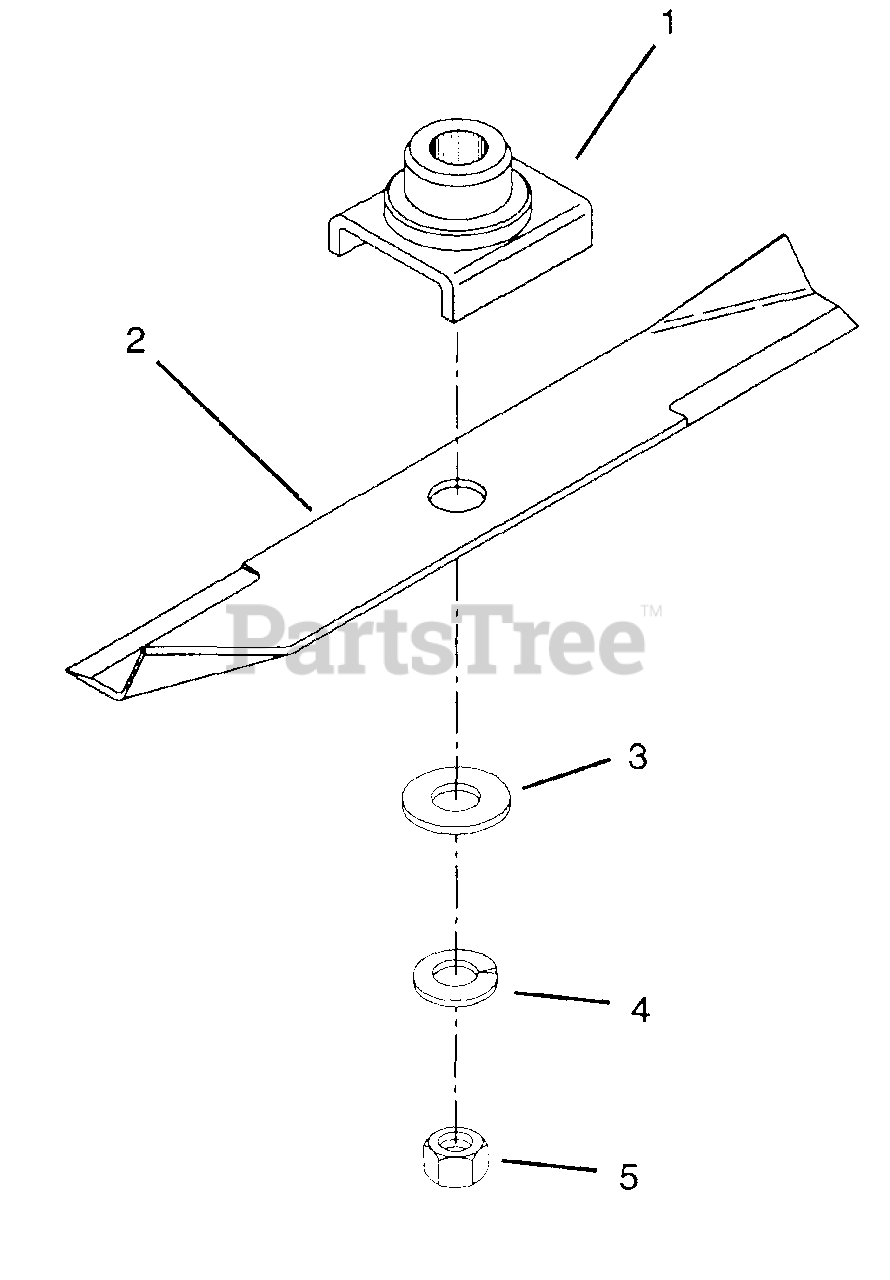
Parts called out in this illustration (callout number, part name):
1	Weldment, Blade Cradle
2	Blade, 60" Sand
3	Washer-Flat-Steel .656 x 1.312 x .095
4	Washer-Lock .625 x .156
5	Nut-Hex .625-11 Grade 2
